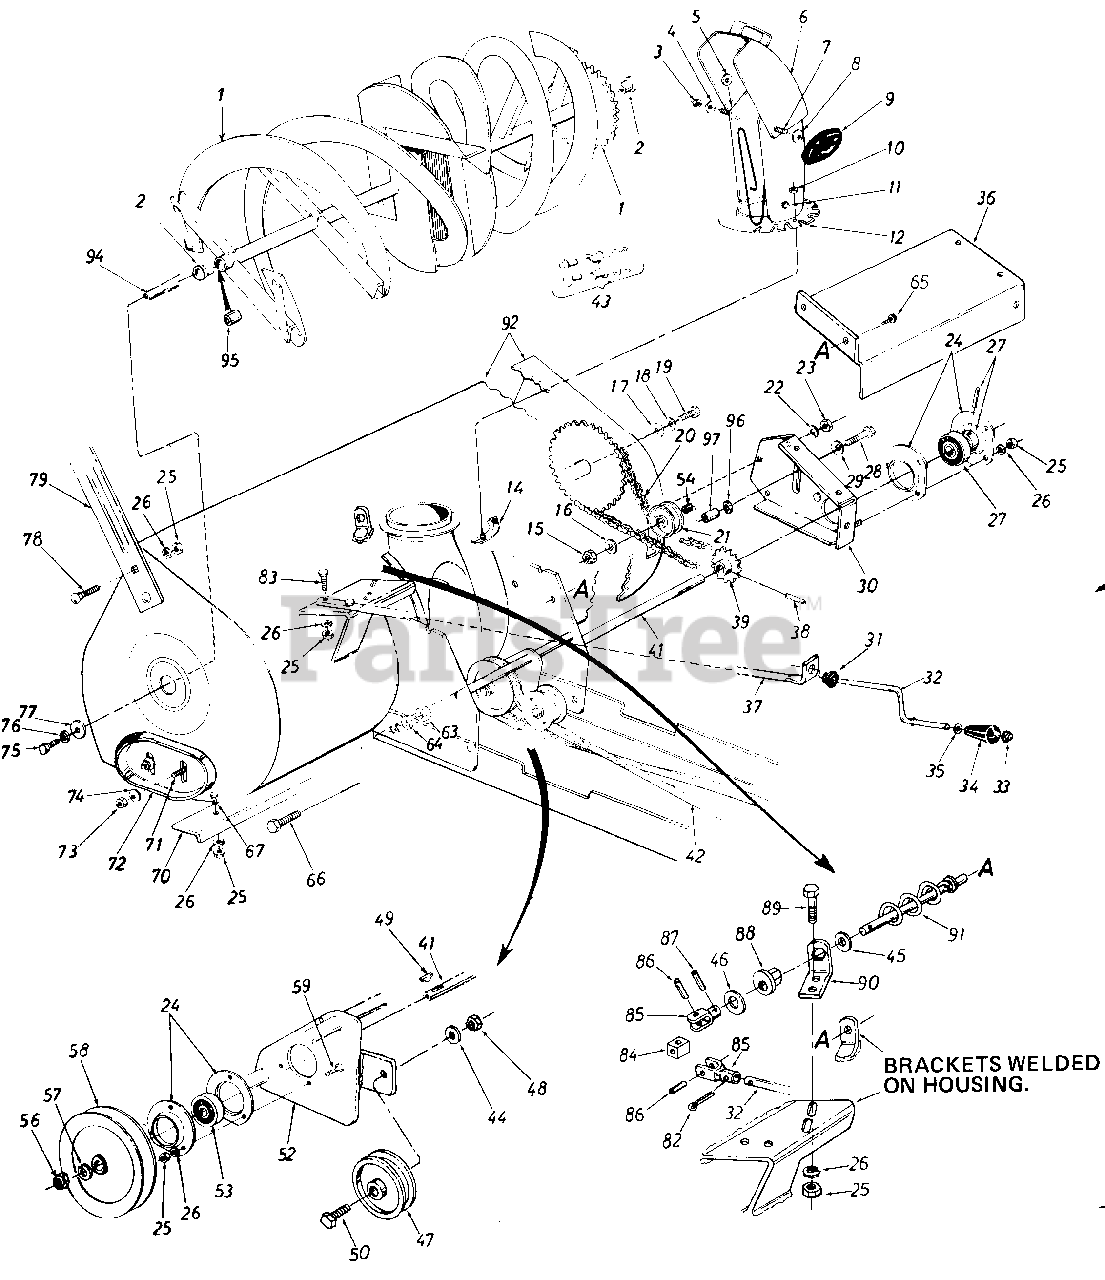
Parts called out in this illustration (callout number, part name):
1	Spiral Ass'y.
2	Flange Bearing
3	Hex Cent. L.-Nut 5/16-18 Thd.
4	Belleville Wash. 3/8" I.D.
5	Flat Washer 3/8" I.D.
6	Top Chute Ass'y.
7	Carriage Bolt 5/16-18 x .62" Lg. *
8	Belleville Wash. 3/8" I.D.
9	Hand Knob
10	Hex Cent. L.-Nut 1/4-2 Thd.
11	Push CaD.188" Dia. Rod
12	Chute Ass'y.
14	Chute Flange Keeper Ass'y.
15	L.-Nut 3/8-16 Thd.
16	F I .-Wash.
17	Fl.-Wash.
18	Belleville Wash.
19	Hex Bolt 1/2-13 x 1.00" Lg.*
20	#420 Chain 1/2" Pitch x 77 Links
21	Plastic Idler 2.00" O.D.
22	L.-Wash. 1/4" I.D.*
23	Hex Nut 1/4-20 Thd. *
24	Bearing Housing
25	Hex Nut 5/16-18 Thd.*
26	L.-Wash. 5/16" I.D.*
27	Self-Aligning Bearing
28	Hex Bolt 3/8-16 x 1.75" Lg.*
29	Belleville Wash. 3/8" I.D.
30	Chain Guard Ass'y.
31	Grommet
32	Chute Crank .375 Dia. x 39" Lg.
33	Push Nut 3/8" Rod
34	Knob 3/8" Dia. Hole
35	Flat Washer
36	Drive Shaft Cover
39	14 Teeth Sprocket Ass'y.
41	Drive Shaft
42	"V"-Belt 1/2" x .88" Lg. (Kevlar)
43	Master Link for #420 Chain
44	L.-Wash. 3/8" I.D.*
45	Fl.-Wash. .385 I.D. x .62"O.D.
46	Fl.-Wash. .390 I.D. x 1.50"O.D.
47	Fl.-Idler with Flanges
48	Hex Jam L.-Nut 3/8-26 Thd.
49	#61 Hi-Pro Key
50	Hex Bolt 3/8-16 x 1.50" Lg.*
52	Spiral Housing Ass'y.
53	Self-Aligning Bearing
54	Sleeve Bearing .50" I.D.
56	Hex Nut 3/4-10 Thd.
57	L-Wash. 3/4" I.D
58	" V "-Pu I ley .750" I.D. x 6.00" O.D.
59	Hex Sems Bolt 5/16-18 x .75" Lg. *
63	Hex L.-Nut 1/2-20 Thd.
64	L.-Wash. 1/2" I.D.*
65	Hex Wash. Hd. Tap Scr. 1/4-20 x .50" Lg.
66	Hex Bolt 1/2-20 x 1.25" Lq.*
67	Carriage Bolt 5/16-18 x .62"*
72	Skid Shoe
73	Hex Nut 3/8-16 Thd.*
74	Belleville Wash. 3/8" I.D.
75	Hex Bolt 1/2-13 x 1.00" Lg.*
76	BellevilleWash. 1/2" I.D.
77	Fl.-Wash.
78	Carriage Bolt 5/16-18 x .62" Lg. *
79	Drift Cutter
82	Cotter Pin 3/32" Dia.
83	Hex Bolt 5/16-18 x 1.50" Lg. *
84	Joint Block
85	Joint BracketAss'y.
86	Spring Pin Roll 3/16" Dia. x .75" Lg.*
87	Spring, Pin Roll 1/8 Dia. x .75" Lg.*
88	Hex Bushing .385 I.D.
89	Carriage Bolt 5/16-18 x .62
90	Chute Crank Bracket
91	Chute Crank Ass'y.
92	Spiral Housing Ass'y.
94	Spiral AxleAss'y.
95	Sleeve Bearing
96	Flat Washer
97	Idler Spacer
